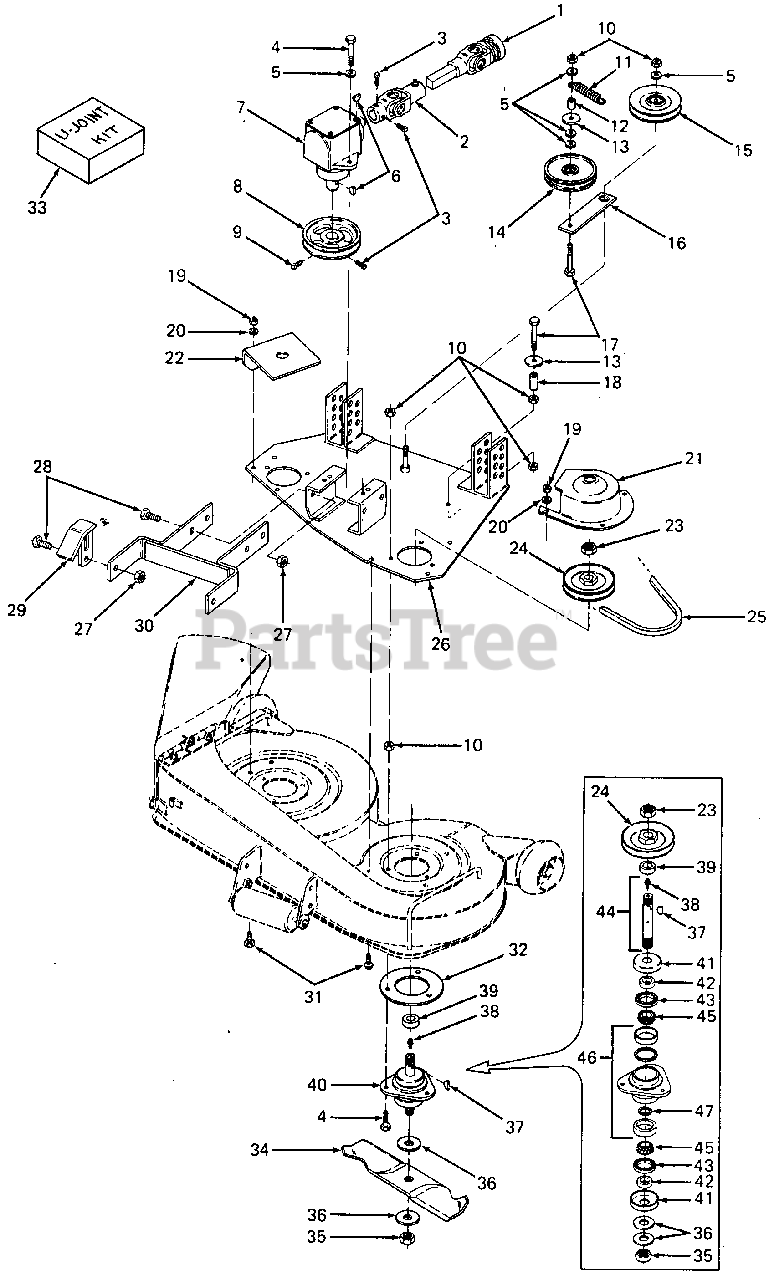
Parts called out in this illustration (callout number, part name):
1	Driveshaft, Quick Disconnect Yoke
2	Driveshaft, Female
3	Setscrew, 5/16-18 x .50 Sq Hd Cup
4	Screw, Hex Cap, 3/8-16 X 1-1/2 Lg GR 5
5	Washer, Flat, .385 X .870 X .090 Thk
6	Key, Hi-Pro, 3/16 X .75 HDN
7	Gearbox, Right Angle
8	Pulley, Deck Gearbox
9	Setscrew, 5/16-18 X 5/8 Sq Hd Cup
10	Nut, Hex Center Lock, 3/8-16
11	Spring, Idler Extension
14	Pulley, Idler
15	Pulley, Idler
16	Idler Assembly
17	Screw, Hex Cap, 3/8-16 X 2-3/4 Lg
19	Nut, Hex Center Lock, 5/16-18
20	Washer, Flat, .344 X .875 X .063 Thk
21	Cover, Belt, LH
22	Cover, Belt, RH
23	Nut, Hex Jam, 3/4-16 GR5
24	Pulley, V, 4.625 X 75
26	Plate, Deck, 32"
27	Nut, Hex Center Lock, 1/2-13
28	Screw, Hex Cap, 1/2 X 13 X 1 Lg GR5
29	Hanger Assy, Deck w/Graphic
31	Screw, Tapping, 5/16-18 X 1.0
32	Ring, Spindle
33	Kit, U-Joint Service
35	Nut, Hex, 3/4-16 GR8
36	Washer, Flat, .781 X 2.0 X .105 Thk
37	Key, Woodruff, #91-1/4
38	Fitting, Lube, 3/16 Drive
39	Spacer, .75 X 1.38 X .56 Lg
40	Spindle Service Kit
41	Cut, Spindle HDN
42	Spacer, .755 X 1.25 X .44 Lg
43	Seal, Oil, 1.25 X 1.874 X .25
44	Kit, Spindle w/Seal
45	Cone, Bearing, Timken
46	Housing, Spindle w/Cups
47	Spacer, Bearing, Timken
